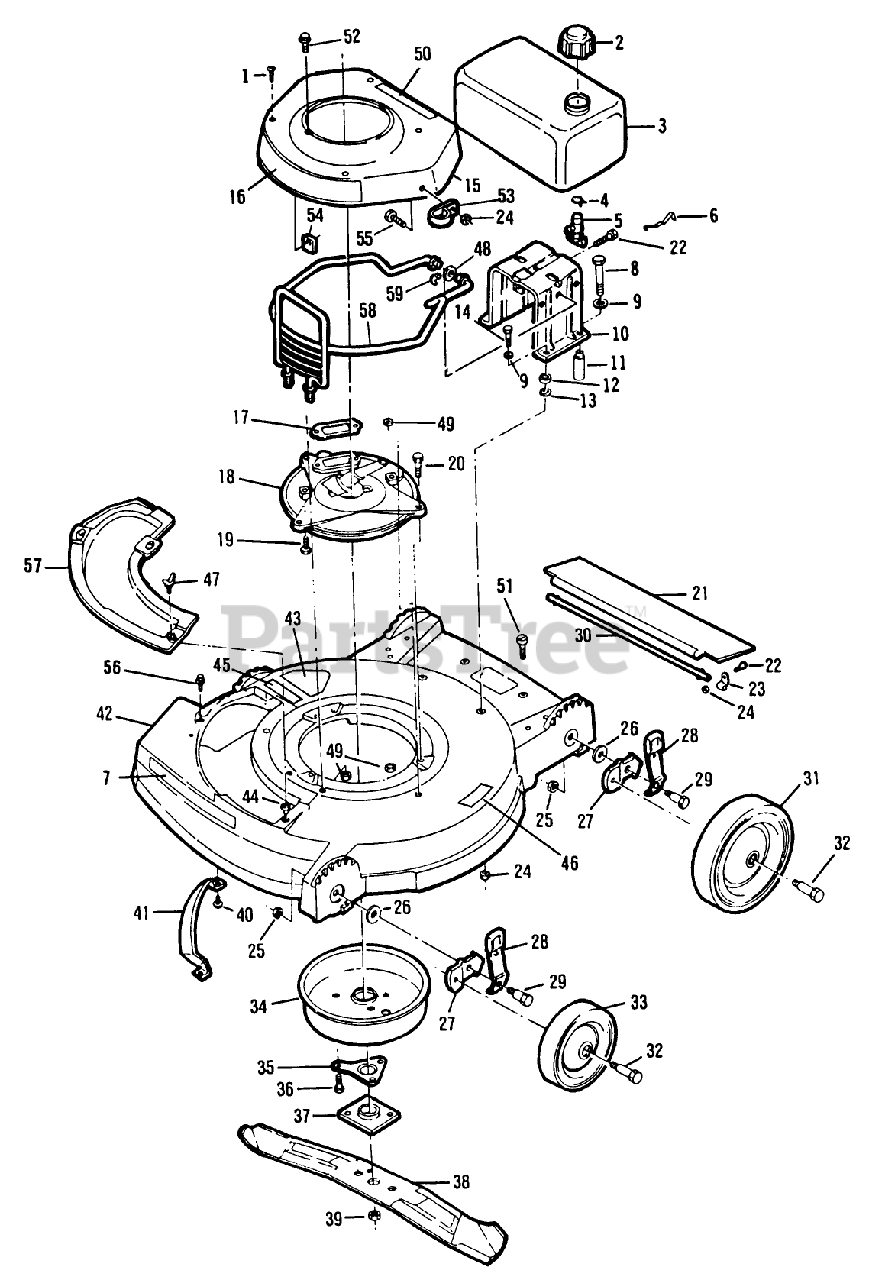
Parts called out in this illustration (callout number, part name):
1	SCREW - SELF TAPPING
2	FUEL CAP & INSERT
4	CLAMP - HOSE S
5	VALVE&SCREEN SM
6	SPRING
9	WASHER
13	WASHER
14	BOLT PIONEER
18	PLATE F
19	SCREW V
20	SCREW-HH
21	T/SHIELD GEAUGA
23	CLAMP ROD KMC
24	LOCKNUT E
25	LOCKNUT
26	WASHER
28	SPRING ARM ASM
29	BOLT
30	ROD 21" ADVANCE
31	WHL & TIRE AY
32	BOLT-SHOULDER
33	WHEEL & TIRE ASSY
34	MUFFLER COVER F
35	SUPPORT F
36	SCREW
37	PLATE AND COLLAR ASM
39	NUT-BLADE
41	BAR-TOE
47	WING SCREW LAWRE
48	WASHER SPRING LAR
49	NUT-LOCK F
52	SCREW SEMS SM
54	PUSHNUT F
59	HAIR PIN
